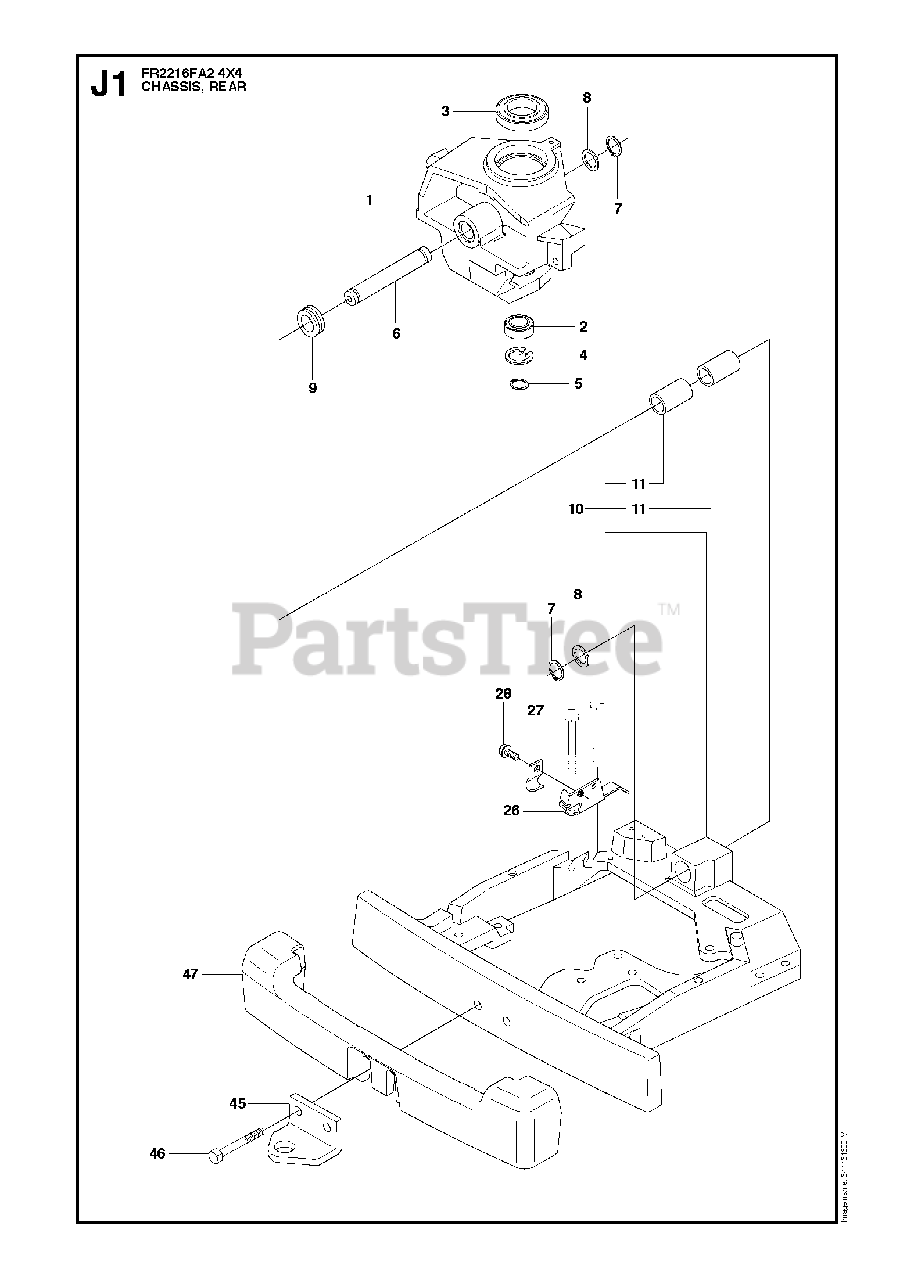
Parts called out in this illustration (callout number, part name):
2	BALL BEARING 6005-2RS
3	BALL BEARING 6010 2RS1
4	CIRCLIP SGH 47
5	RETAINING RING SGA 25
7	RETAINING RING SGA 25
11	BUSHING
45	DRAW RING
